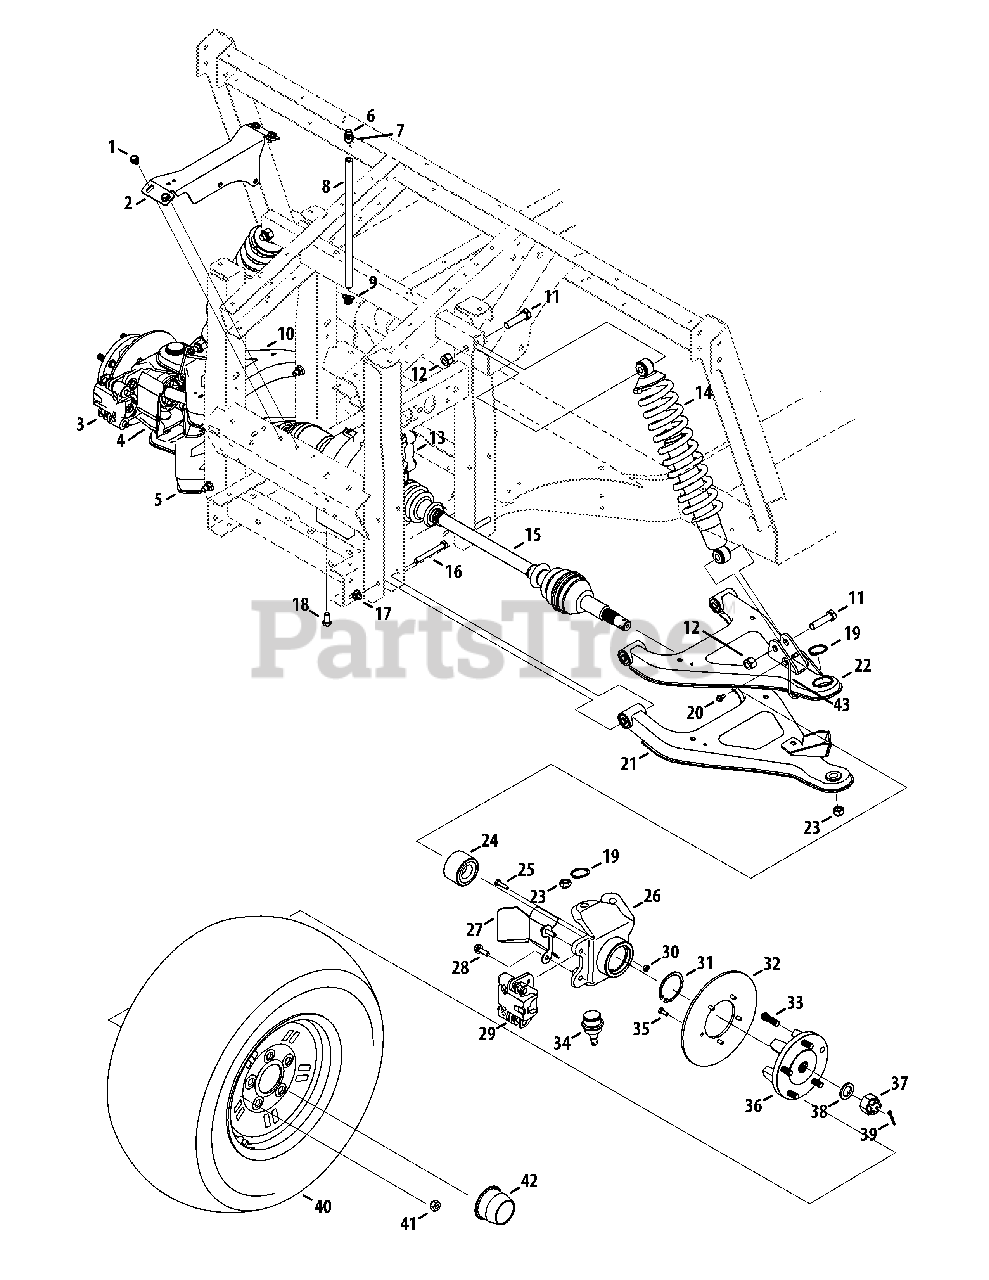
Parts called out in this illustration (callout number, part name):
1	Screw, tt, 5/16-18 x 0.500
2	Front Mount, differential, 4x4
3	Brake, hydraulic, caliper, frt, RH
4	Housing, knuckle, r/frt, mach
5	Control Assembly, r/frt, lower
6	Vent,3/8 Dia
7	Clamp, hose, .490 Dia.
8	Hose, Fuel Line
9	Clamp, Hose, Adj.
10	Arm Assembly, r/frt, upper
11	Screw, 1/2-13 x 2.00, gr5, std
12	Nut, Hex Lock, 1/2-13, Nylon
13	Differential Assembly, cfd, 4x4
14	Shabs, 5.0 Stroke, front
15	Axle Assembly, cv Joint, 4x4
15	DOJ Boot Kit (Incl. clamp)
15	Rzeppa Boot Kit (Incl. clamp)
16	Screw, 3/8-16 x 3.00, gr8, std
17	Nut, Flange Lock, 3/8-16, Nylon
18	Screw, 3/8-16, .75, gr5, std
19	Ring, retainer, 34 x 1.6
20	Screw, tt, 1/4-20 x .500
21	Control Assembly, l/ftr, lower
22	Control Assembly, l/frt, upper
23	Nut, Nylock, m12 x 1.25
24	Bearing, dble Row, 60x30x37
25	Screw, 1/4-20 x 1.00, gr5, spec
26	Housing, knuckle, l/frt, mach
27	Bracket, Steering Shield, LH
27	Bracket, Steering Shield, RH
28	Screw, m8-1.25, 25.00
29	Brake, hydraulic, caliper, frt, LH
30	Nut, Hex, 1/4-20, gr5
31	Ring, retainer, dho-60
32	Disc, brake, 8.00x.188
33	Stud, rib Neck, 7/16-14 x 1.6
34	Ball Joint, 14d-6201
35	Screw, 1/4-20 x .625, gr5, lock
36	Hub, wheel
37	Nut, slotted, 22x1.5
38	Washer, flat, .88 x 1.38 x .125, ht
39	Pin, cotter, 5/32, 1.25
40	Wheel Assembly, rh, 25 x 10-12
40	Wheel Assembly, rh,25x10-12, blk
40	Wheel Assembly, lh, 25 x 10-12
40	Wheel Assembly, lh,25x10-12, blk
40	Tire Only, 25 x 10-12
41	Nut, lug, 7/16-14
41	Nut, lug, 7/16-14, Chrome
42	Cap, Wheel
42	Cap, Wheel, Chrome
43	Wire, Brake Line
